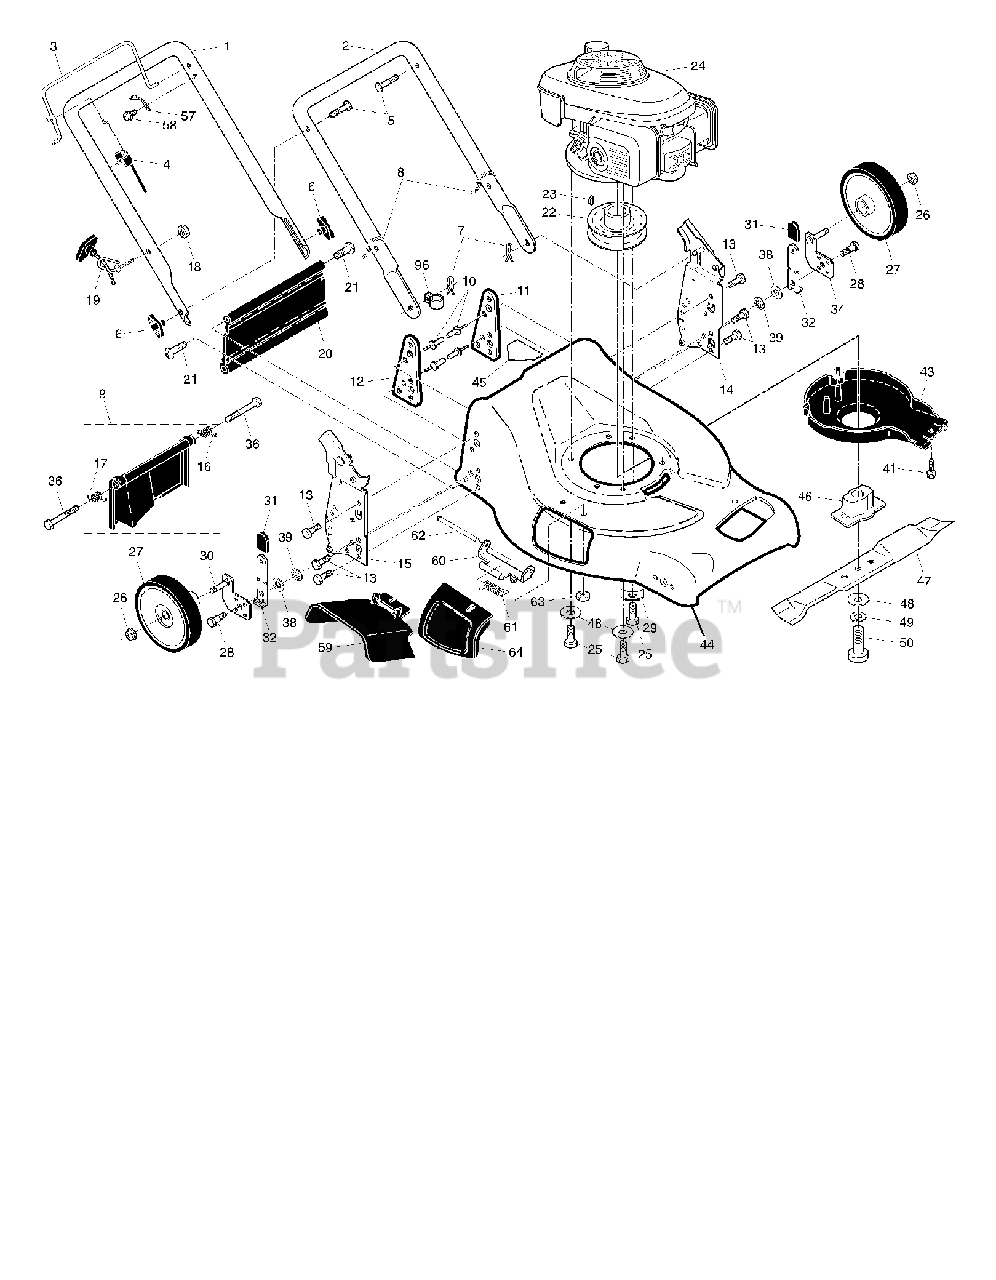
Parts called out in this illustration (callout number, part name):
1	HANDLE.UPER.D.ST.EZ
2	LOWER HANDLE
3	Dstrt Bail, Fl Aw Cras Blk
4	CABLE.MZR
5	BOLT, HANDLE 5/16-18X1.75
6	Knob Handle, Black
7	HAIRPIN COTTER
8	TIE GUIDE
9	REAR DOOR KIT.
10	RIVET BLIND
11	LH BRACKET SUPPORT
12	RH SUPPORT BARCKET
13	SCREW 14-20 X 5/8
14	BRKT.ASM.HND.21FG
15	BRKT.ASM.HND.21FG
16	SPRING LH
17	SPRING.REAR.DOOR.EZ.21
18	NUT
20	Skirt, Rear 21" Fwgd Black
21	HINGE SCREW
22	ENGINE PULLEY
23	HI-PRO KEY
24	Poulan TBD
25	BOLT 3/8-16X1-1/8
26	HEX FLANGE LOCKNT
27	Wheel, 8" X 1.75 5-Spoke Marig
30	ARM.ASM.AXLE.RR.BZP
31	Knob
32	SELECTOR SPRING
34	ARM.ASM.AXLE.LR.BZP
39	PUSH NUT
41	SCREW.HEX.WSH
43	DEBRIS.SHIELD.FWGD.WALK.MOWER
44	LAWN MOWER HOUSING
45	DECAL HYT
46	ADAPTER.BLADE
47	BLADE, 21" MULCH
48	WASHER,HARDEN
50	SCREW, HEX HD 3/8-24 X 1-3/8
57	BRACKET.UPSTOP
59	DISCHARGE DEFLECTOR
60	BRACKET.ASM.HINGE.21.FWGD.
61	Torsion Spring
62	ROD.HINGE.21
63	LOCKNUT.NYLOC.1/4-20
64	DOOR.MULCH.21.REAR
